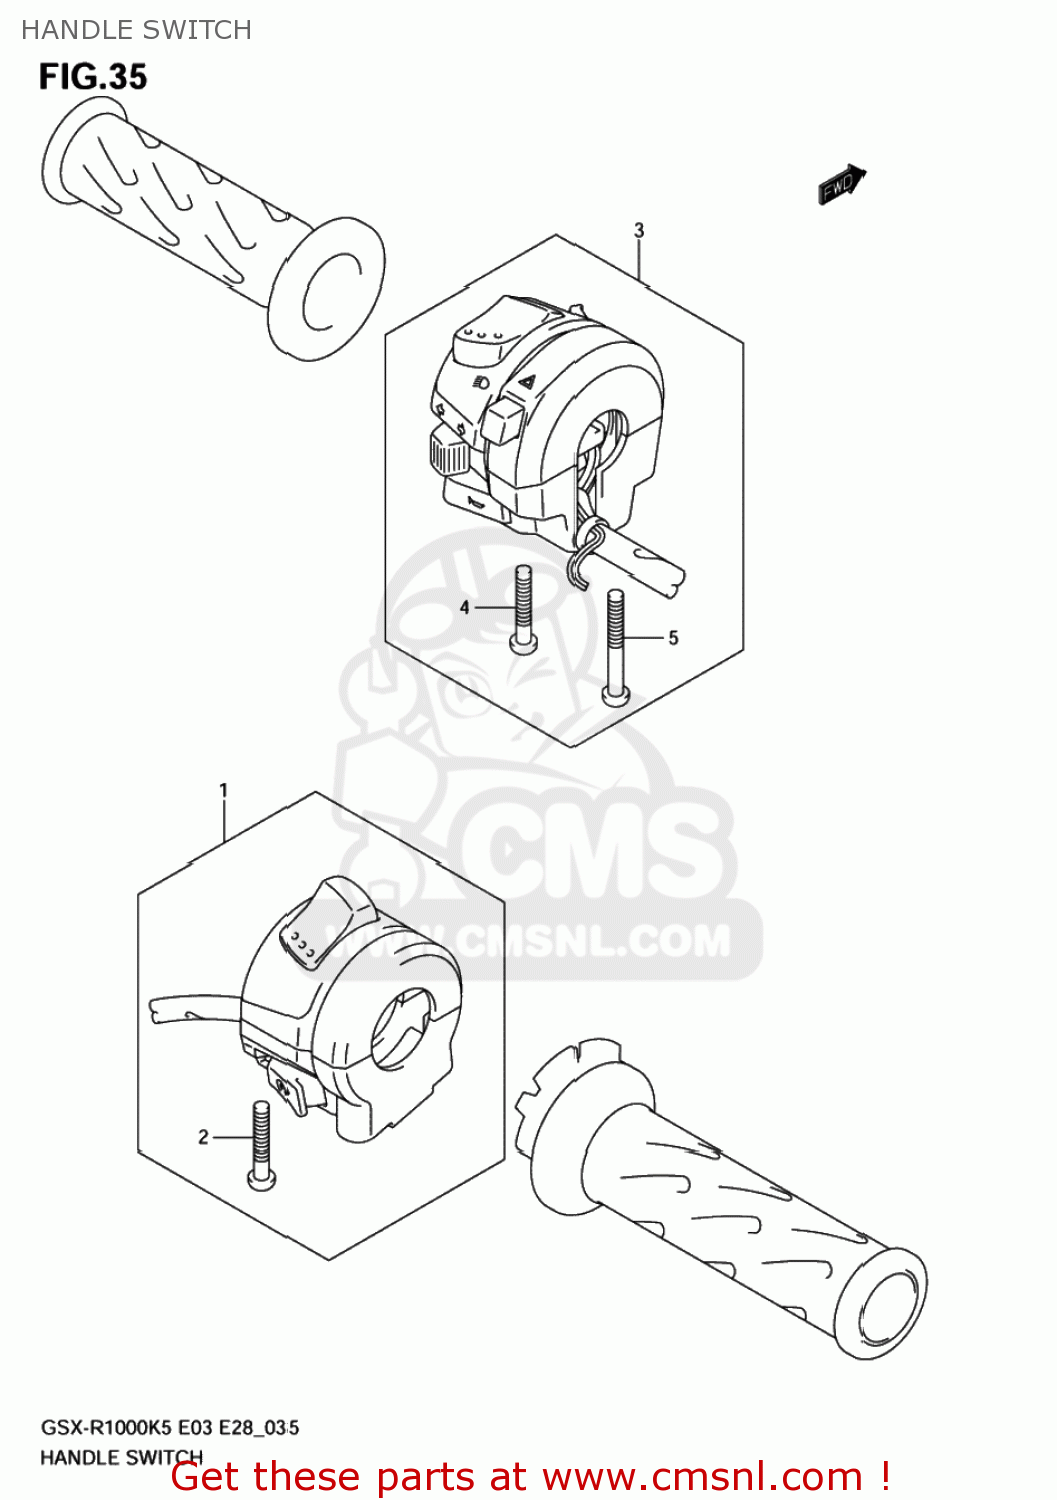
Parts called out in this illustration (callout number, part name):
1	SWITCH ASSY,HANDLE,R
2	SCREW
3	SWITCH ASSY,HA
4	SCREW
5	SCREW
